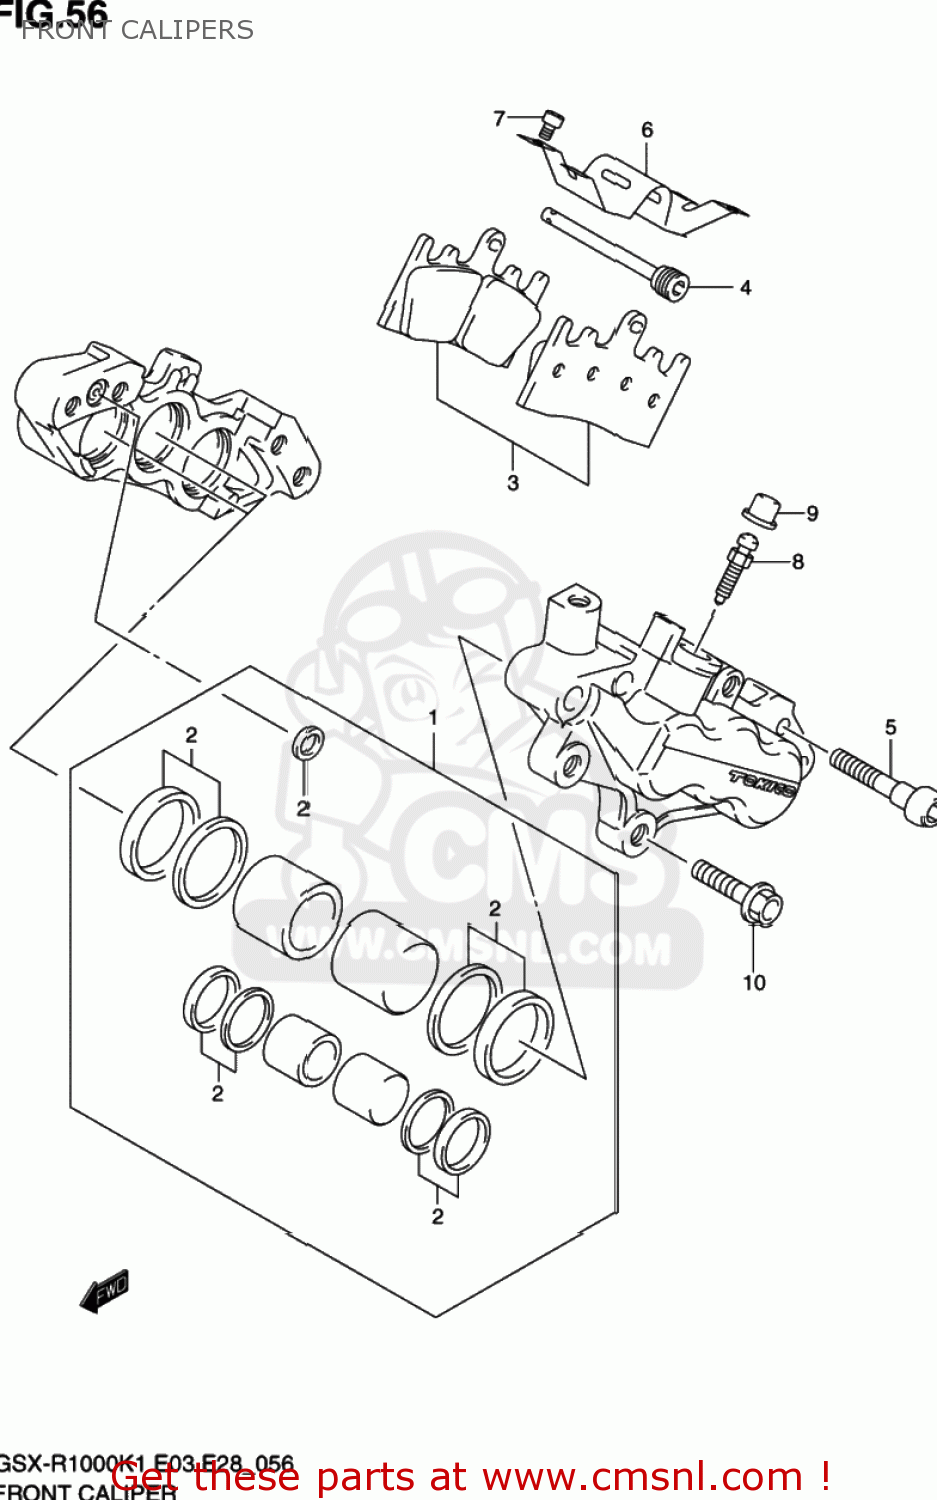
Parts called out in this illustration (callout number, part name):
1	PISTON SET
2	SEAL SET,PISTO
3	PAD SET (NAS)
4	PIN,PAD
5	BOLT
6	COVER,CALIPER
7	SCREW
8	BLEEDER
9	CAP,BLEEDER PLUG
10	BOLT(8X28)
